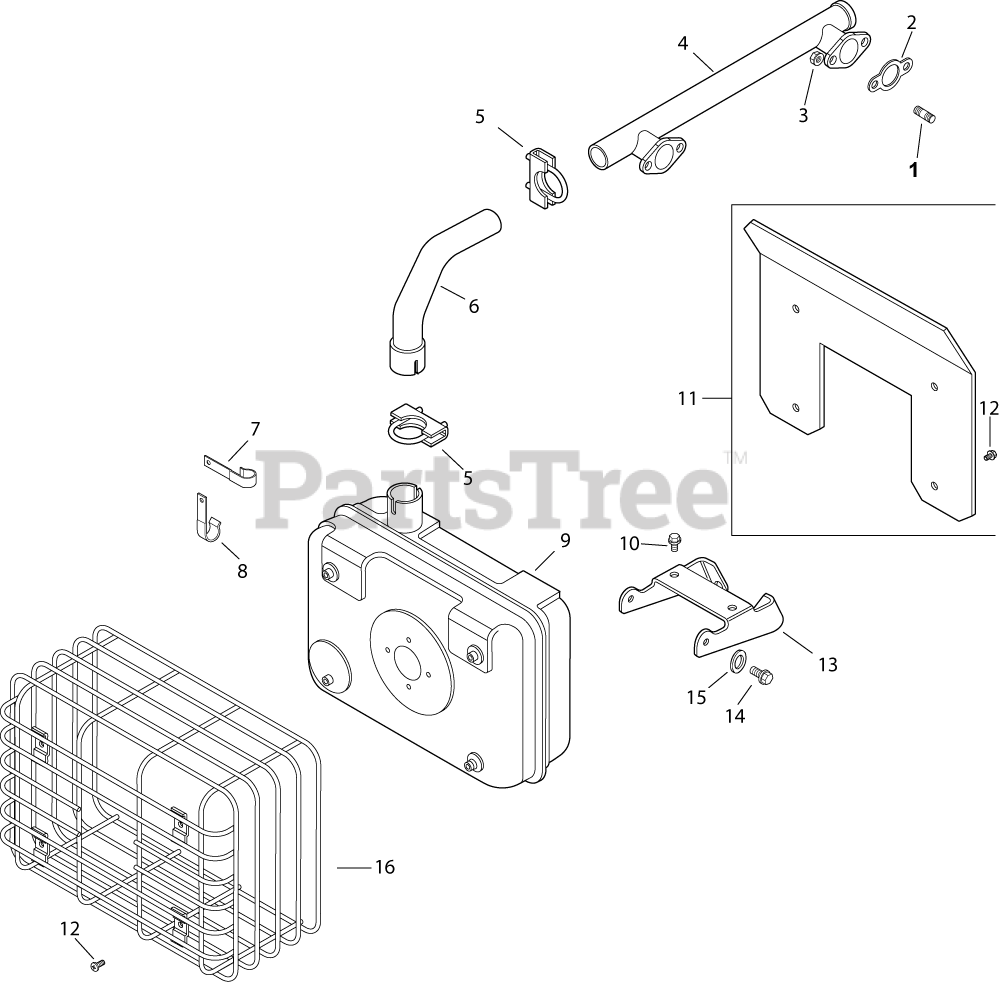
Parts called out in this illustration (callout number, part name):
1	STUD, EXHAUST-USE 25 072 24-S
2	GASKET, EXHAUST
3	NUT, FLG M8X1.25
4	MANIFOLD, EXHAUST
5	CLAMP, MUFFLER
6	PIPE, EXHAUST
7	CLIP, CABLE - USE 24 154 10-S
8	CLIP, CABLE
9	MUFFLER, SIDE MOUNT - USE 24 068 153-S
10	SCREW, FLG M8X1.25X20
11	KIT, HEAT SHIELD
12	SCREW, HVY FLG M5X.8X10
13	BRACKET, MUFFLER
14	SCREW,FLG THD FRM M6X1.0X16-(#25086397S)
15	WASHER, SPRING LOCK 1/4"
16	GUARD, MUFFLER
